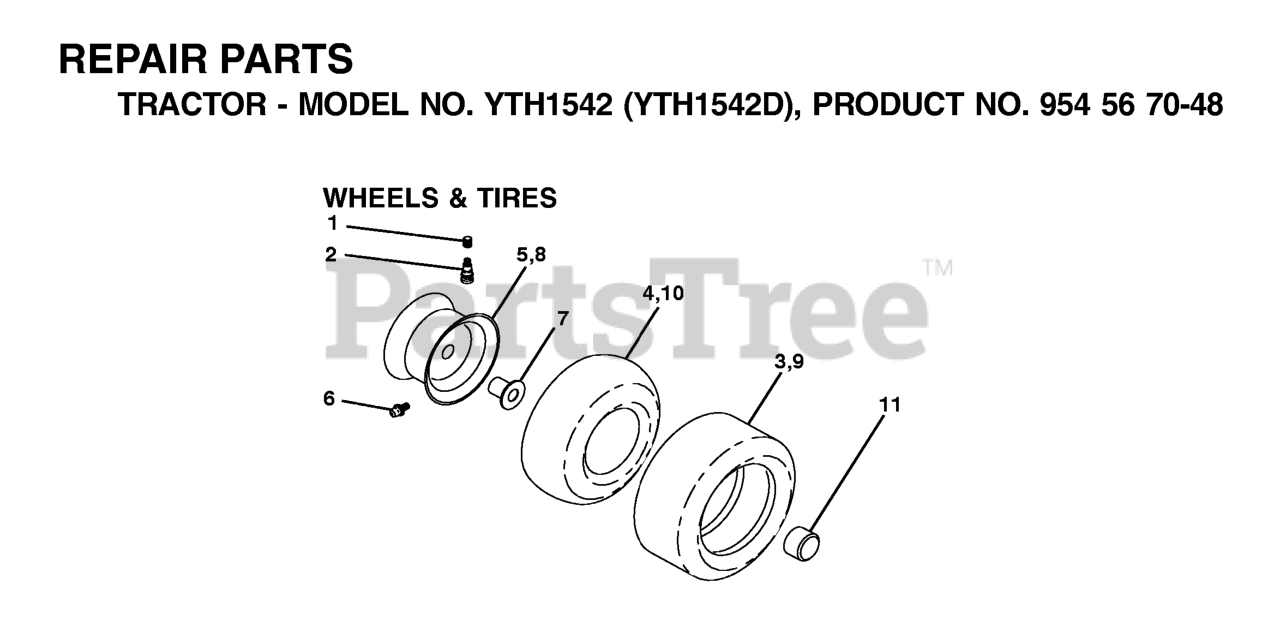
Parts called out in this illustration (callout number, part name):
2	VALVE STEM LT
3	TIRE HEAVY DUTY
4	TUBE.5.3/4.5/6
5	RIM ASM 6" FRONT SILVER
6	FITTING LT
7	BEARING T
8	RIM ASM 8" REAR SILVER
9	TIRE.TS.20X10-8
10	TUBE
11	CAP, AXLE BLK
